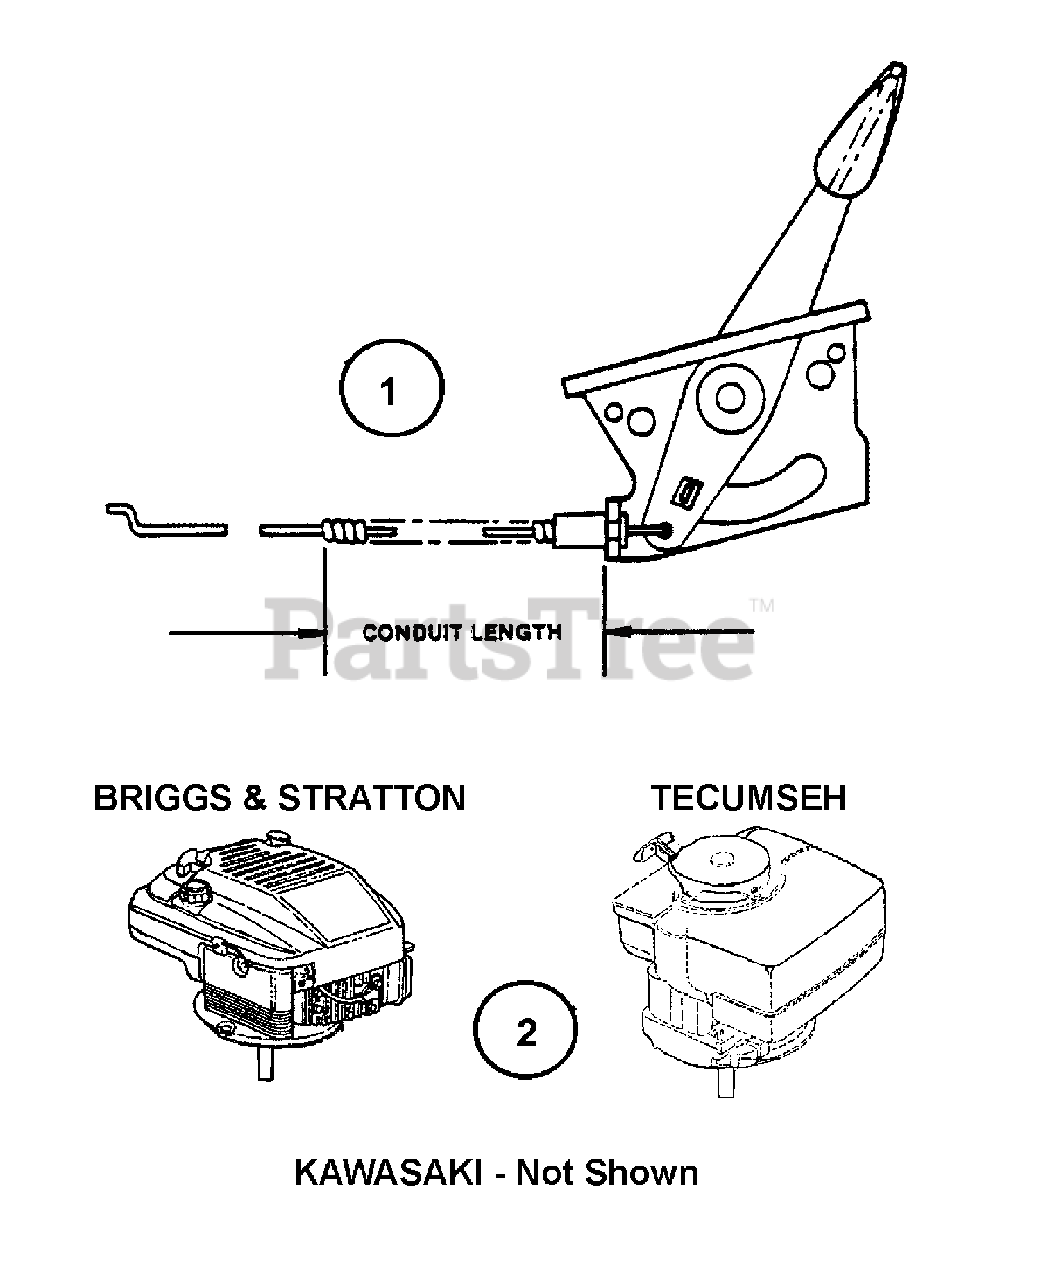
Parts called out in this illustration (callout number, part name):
1	CONTROL, Throttle (Briggs 4 cycle, 48" with choke detent)
1	CONTROL, Throttle (Briggs 4 cycle, 48" without choke detent)
1	CONTROL, Throttle (Briggs OHV 4 cycle, 49.75")
1	CONTROL, Throttle (Tecumseh 2 cycle, 54.5")
1	CONTROL, Throttle (Tecumseh 4 cycle, 51.5")
2	ENGINE, Briggs (Model 122702-3151-01) 4 HP
2	ENGINE, Briggs (Model 122702-0120-01) 4.5 HP
2	ENGINE, Briggs (Model 124802-3210-01) 5.5 HP
2	ENGINE, Briggs (Model 12F802-0838-01) 5 HP
2	ENGINE, Briggs (Model 128802-0211-01) 5.5 HP
2	ENGINE, Briggs (Model 99772-3624-01) 5.5 HP
2	ENGINE, Briggs (Model 128807-0212-01) 5.5 HP Electric Start
2	ENGINE, Briggs (Model 99772-3111-02) 5.5 HP
2	ENGINE, Briggs (Model 99777-0951-A1) 6 HP Electric Start
2	ENGINE, Briggs (Model 12J802-1520-21) 6 HP
2	ENGINE, Briggs (Model 12J802-1522-A1) 6 HP
2	ENGINE, Briggs (Model 12J802-1528-21) 6 HP
2	ENGINE, Briggs (Model 12J802-1530-21) 6 HP
2	ENGINE, Kawasaki (Model FC-150V-F511) 5 HP
2	ENGINE, Robin (Model EC130V-51110) 4 HP
2	ENGINE, Tecumseh (Model TVXL840-8456E) 5 HP 2 Cycle
2	ENGINE, Tecumseh (Model OVRM60-21803A) 6 HP
